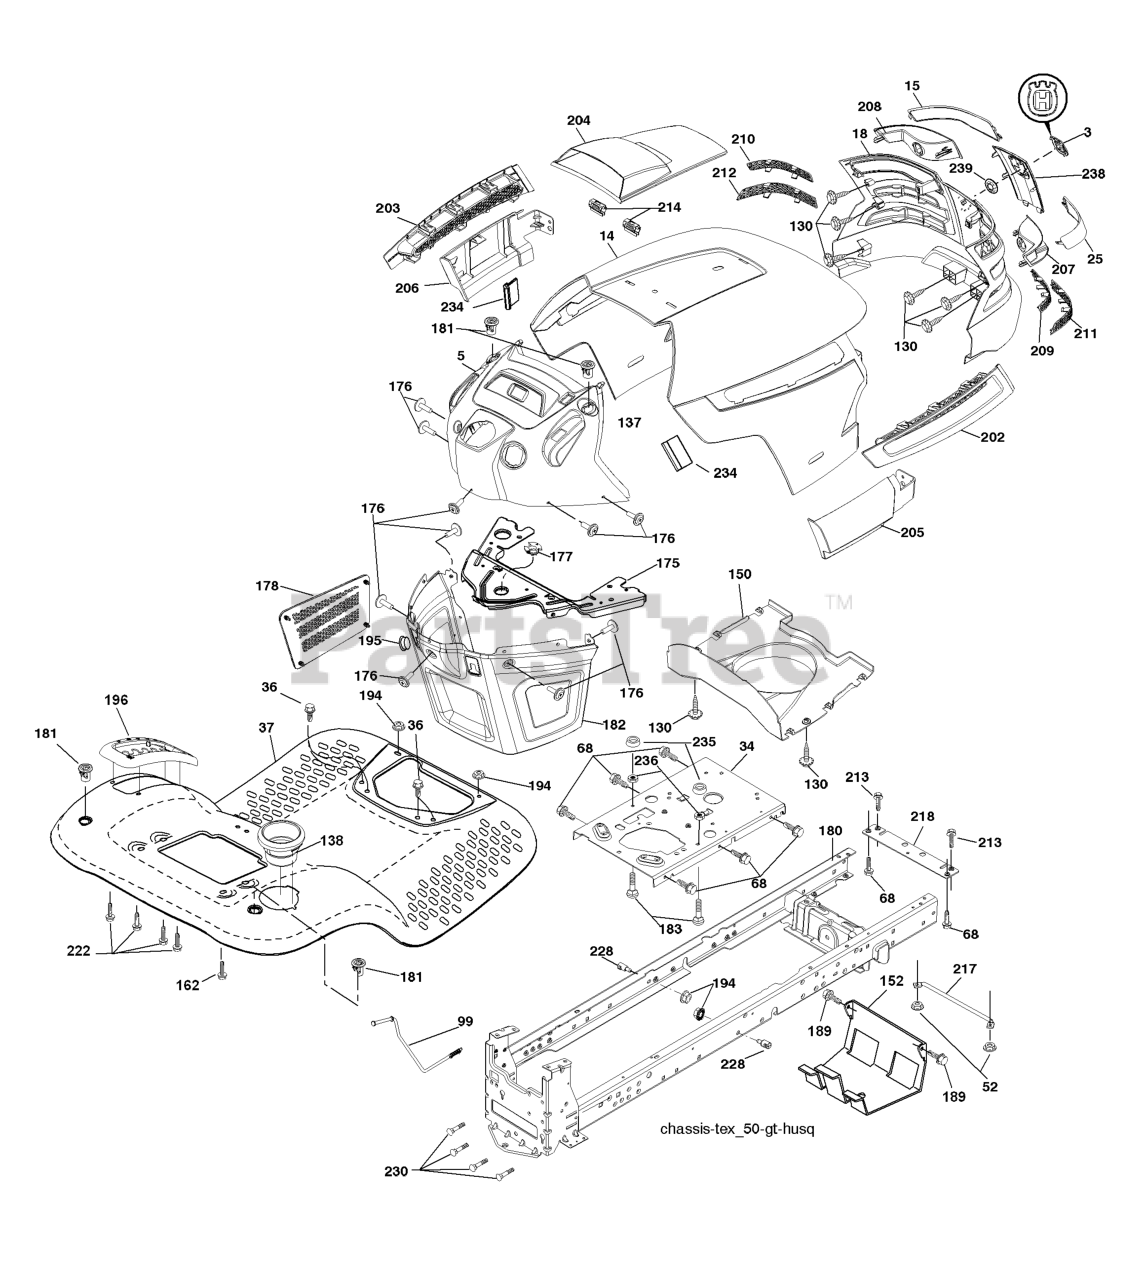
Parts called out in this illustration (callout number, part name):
3	RP LOGO
14	HOOD
15	LENS.LH.TEX.GT.HUSQ.CL
18	GRILL.ASM.HUSQ.TG/CRD.W/TRIM
25	LENS.RH.TEX.GT.HUSQ.CL
34	PLATE.ENGINE.WELDED.CHASSIS
36	SCREW 5/16"
37	FEND/FTRST.PCH.CPH.NFW
52	LOCKNUT
68	Screw 5/16-18 x 1/2
99	ROD ASM BYPASS
130	SCREW
138	CUPHOLDER.TL.TEX.418
150	AIR.DUCT.TEXGT.HUSQ.31
152	SHIELD.BROWNING.W/TEX
162	SCREW.HI-LO.CONSOLE
175	PLATE.CROSSMEMBER.HUSQ
176	SCREW.#10-24X5/8.RN.QU
177	BUSHING, STEERING
178	CARGO.ASM.NET.TXGT.W/C
180	CHASSIS
181	BUSHING.MNT.FEND.CRGO.
182	DASH.LOWER.COMMON.12V.
183	BOLT.5/16-18X1-1/4 FULL.THREAD
189	SCREW
194	NUT LOCK HEX FLANGE 5/16-18
195	PLUG.HOLE.DASH.LOWER.12V.BLK
196	CONSOLE.ASM.DECK.LIFT.
202	VENT.SIDE.HOOD.HUSQ.RH.GREY
203	VENT.SIDE.HOOD.HUSQ.LH.GRAY
204	VENT.TOP.HOOD.HUSQVARN
205	SKIRT.HOOD.SIDE.HUSQ.RH.GREY
206	SKIRT.HOOD.SIDE.HUSQ.LH.GREY
207	BEZEL.RH.TEX.GT.HUSQ
208	BEZEL.LH.TEX.GT.HUSQ
209	INSERT.HEX.GRILL.HUSQ.GREY
210	INSERT.HEX.GRILL.HUSQ.
211	INSERT.HEX.GRILL.HUSQ.
212	INSERT.HEX.GRILL.HUSQ.
213	BOLT
214	CLIP.RETAINER.TINNER.
217	ROD PIVOT CHASSIS/HOOD
218	X-PIECE.HOOD.STOP.NON/
222	SCREW.1/4-20X5/8
228	STUD.FASTNER.W/ANTI-ROTATE
230	SHOULDER BOLT 5/16-18TT
234	BUMPER.HOOD.TEX.HUSQVARNA
235	SPACER FENDER
236	NUT.CENTERLOCK.5/16-
238	TRIM.HUSQ.TG/CRD.SERVICE
239	NUT PUSH M
